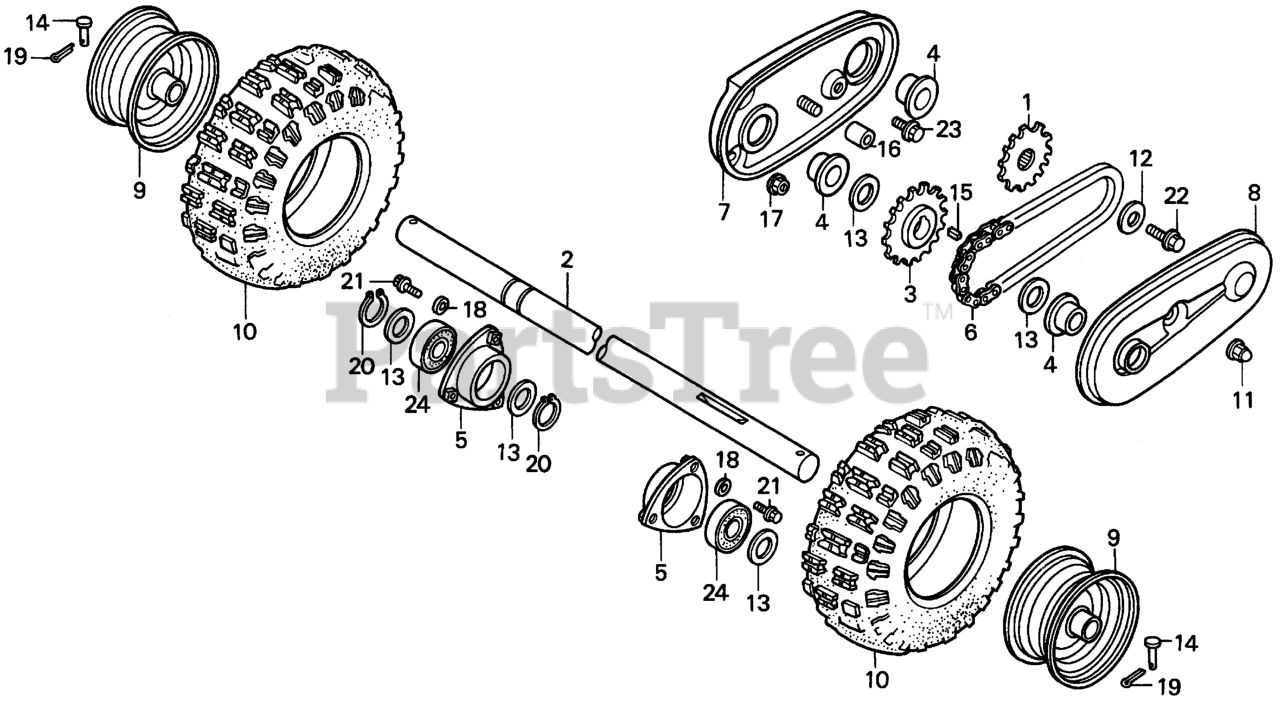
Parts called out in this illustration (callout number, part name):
1	SPROCKET, DRIVE
2	SHAFT, WHEEL
3	SPROCKET, DRIVEN
4	BUSH (26MM)
5	HOLDER, BEARING
6	CHAIN, FINAL (RK420MX40LE)
6	CHAIN, FINAL (420X40)
7	CASE, CHAIN
8	COVER, CHAIN
9	WHEEL (3.00MX5)
10	TIRE SET (11X4.00-5)
11	NUT, CAP (8MM)
12	WASHER, SPECIAL (28X8.5X4.0)
13	WASHER, THRUST (20MM)
14	PIN (6.2X38)
16	COLLAR (12.7MM)
17	NUT, FLANGE (6MM)
18	WASHER, PLAIN (6MM)
19	PIN, COTTER (3.0X18)
20	CIRCLIP (OUTER) (20MM)
21	BOLT, FLANGE (6X12) Use up to Engine SN 1543277.
21	BOLT, FLANGE (6X16) Use from Engine SN 2056820.
22	BOLT, FLANGE (8X20) Use up to Engine SN 1609606.
23	BOLT, FLANGE (10X20)
24	BEARING, RADIAL BALL (6204UU)
